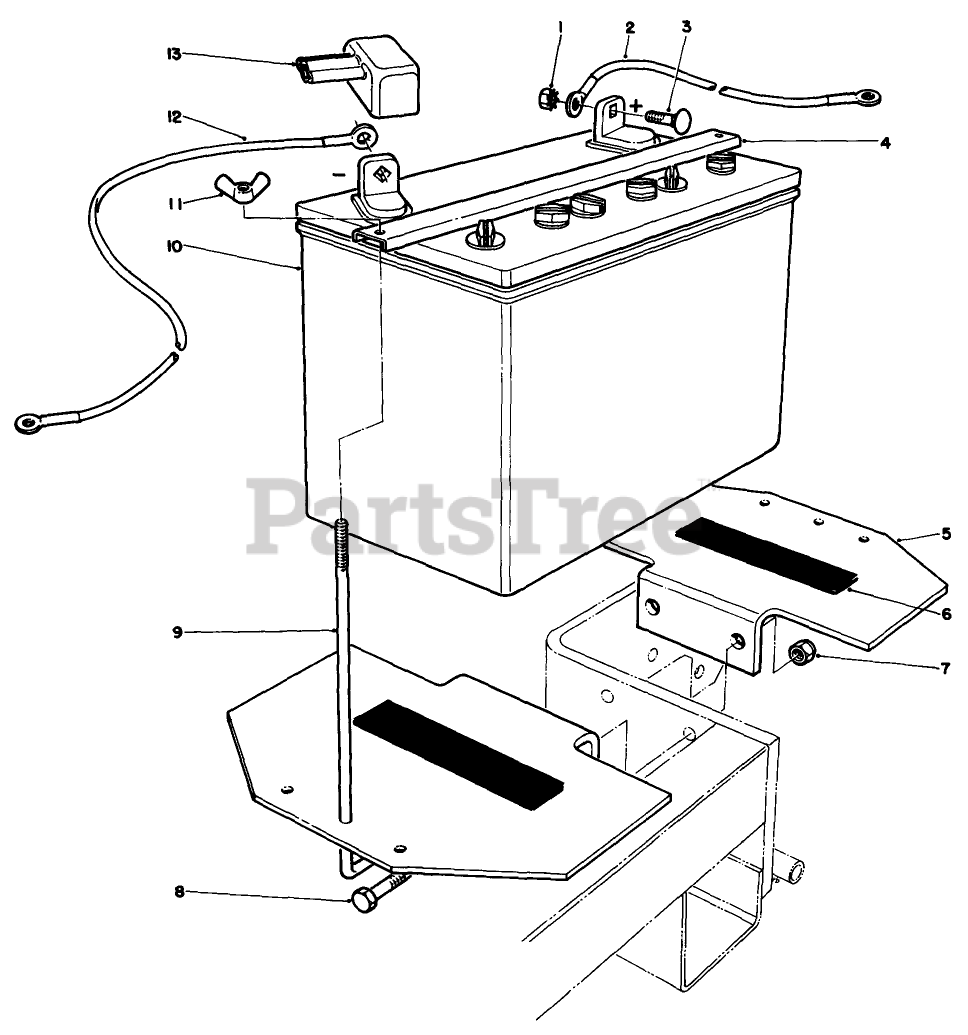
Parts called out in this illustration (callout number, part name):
1	NUT-KEPS
2	WIRE ASM
3	BOLT-CARR
6	PAD-TANK, FUEL
7	NUT-LOCK, NI
8	SCREW-HH
9	ROD-SUPPORT, BATTERY
10	SEE SB MISC 14
11	WING NUT
12	Wire Assy. (Battery to Ground)
13	BOOT-TERMINAL
